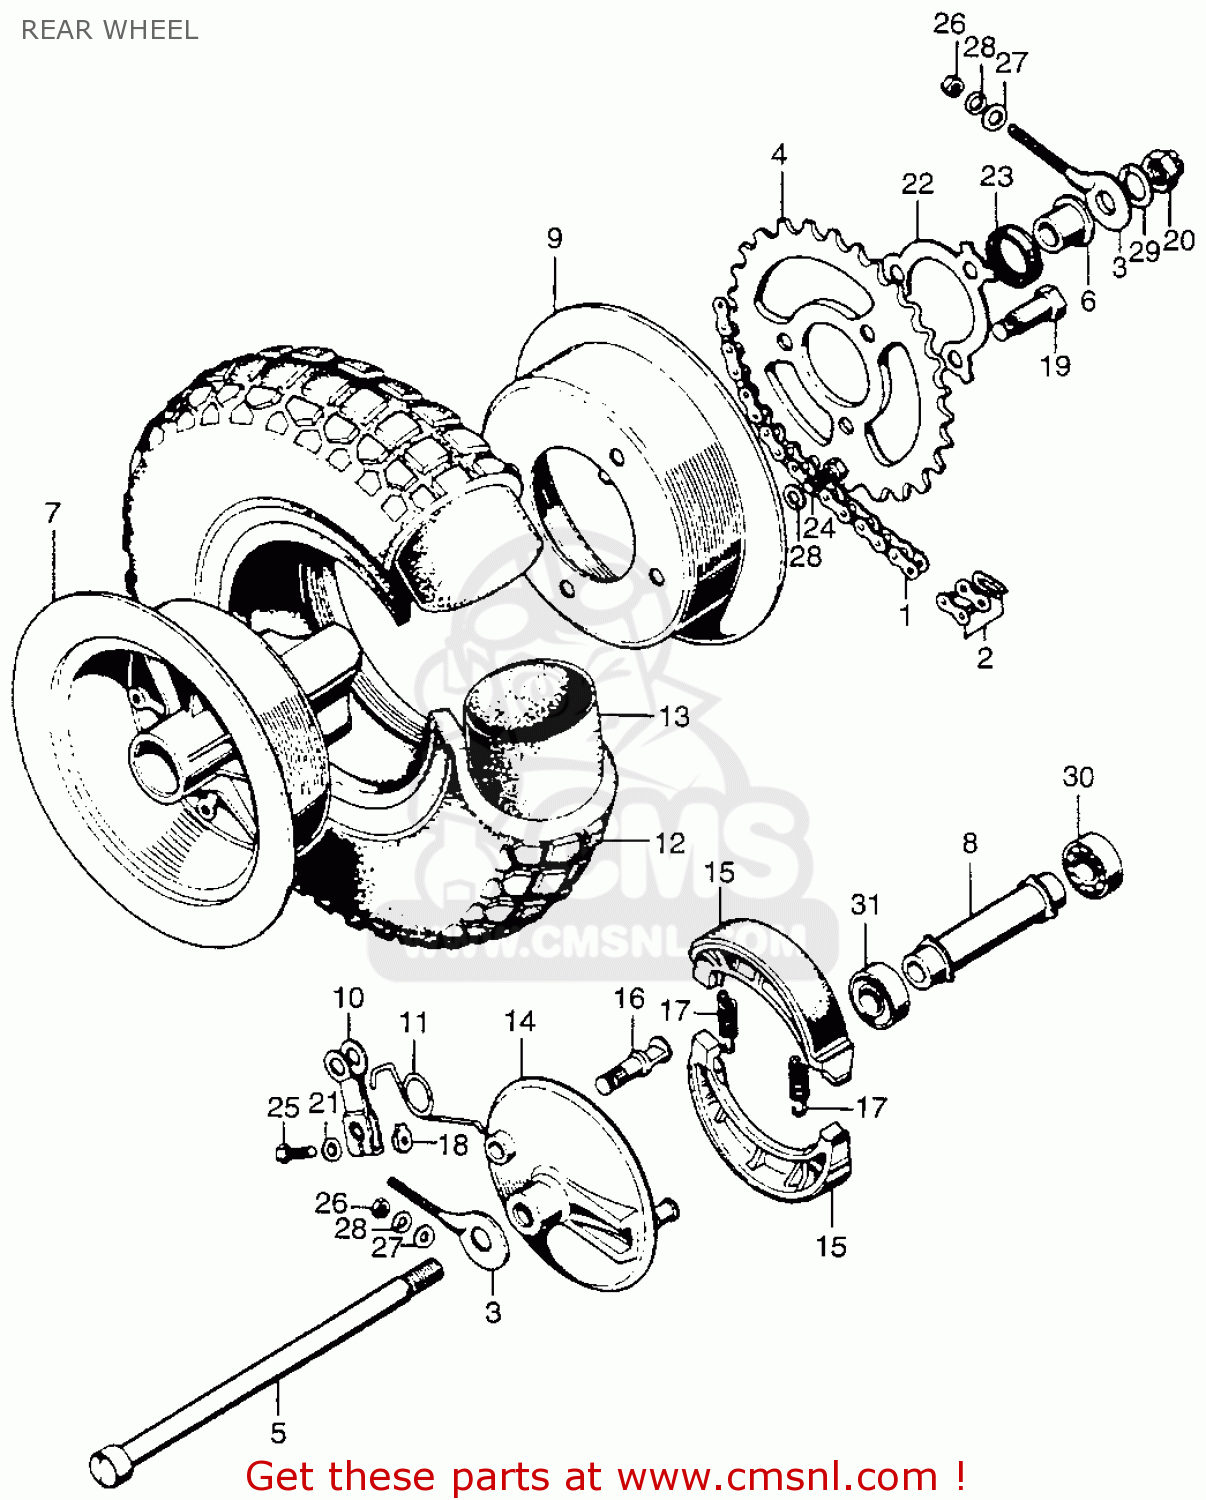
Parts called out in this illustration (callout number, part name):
1	CHAIN,DRIVE
2	JOINT,CHAIN
3	ADJUSTER,CHAIN
4	SPROKET,DRIVEN
5	AXLE,REAR,WHEEL
6	COLLAR,L,REARSIDE
7	HUB,REAR WHEEL
8	COLLAR,REARDISTAN
9	RIM,WHEEL
10	ARM FR,BRAKE
11	SPRING,REARARM
12	TIRE 400-52PTW
13	TUBE (400X5)
14	PANEL,FRONTBRAKE
15	SHOE BRAKE (MCA)
16	CAM FRONT,BRAKE
17	SPRING BRAKE SHOE
18	NUT, BRAKE ARM
19	BOLT,FINALSPROCKT
20	NUT,SELF LOCK
21	WASHER, BRAKE ARM
22	WASHER,8MM
23	OIL SEAL,18X32X8
24	BOLT,HEX 6X16
25	BOLT,HEX 6X25
26	NUT HEX 6MM
27	WASHER PLAIN 6MM
28	WASHER,SPRING,6MM
29	WASHER,SPG 12MM
30	B/BRG RAD N/COM
31	B/BRG RAD N/COM
